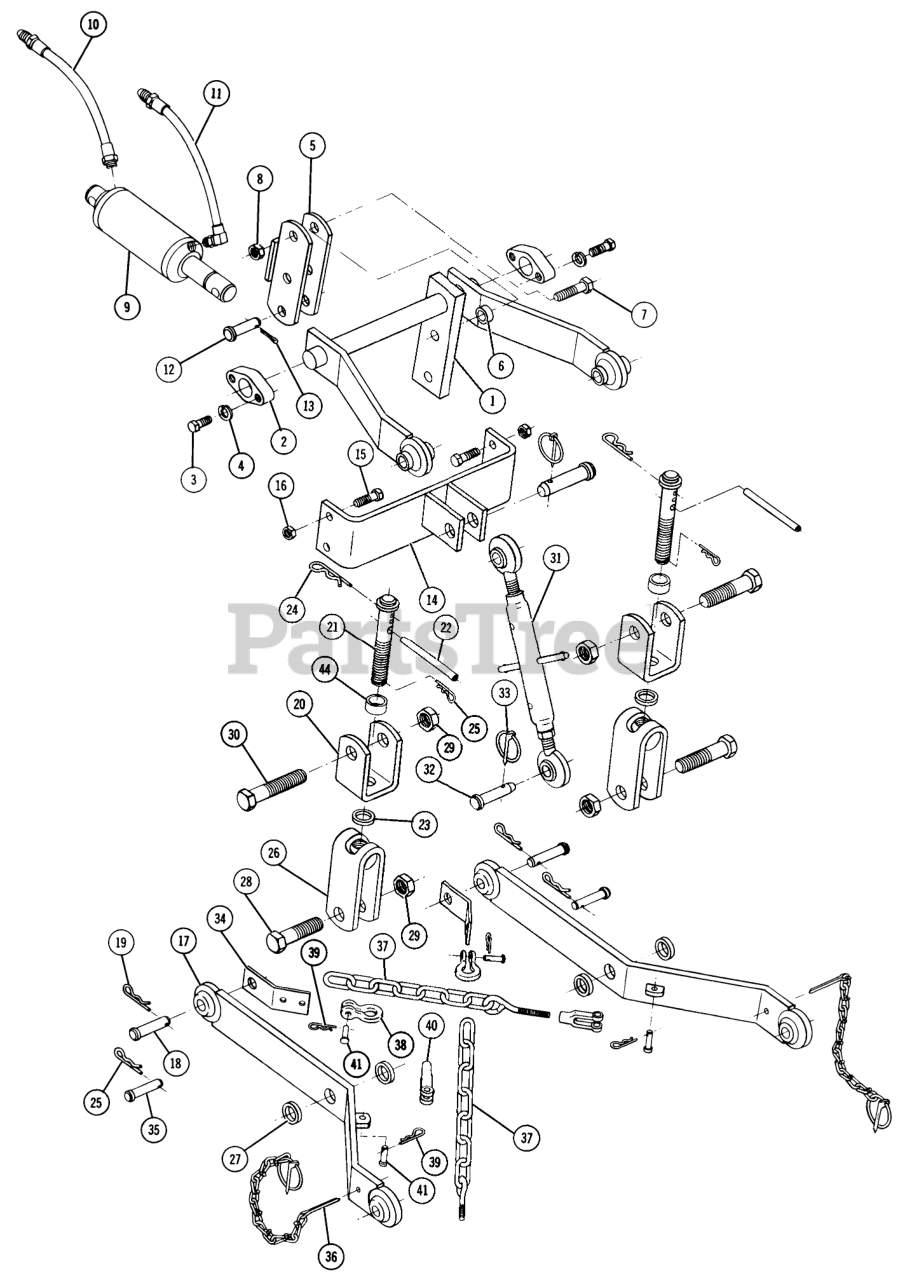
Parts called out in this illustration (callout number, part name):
19	Hairpin
23	WASHER
24	Hairpin
25	Hairpin Cotter
27	SPACER
32	PIN HITCH UPPER LINK
40	CLEVIS
